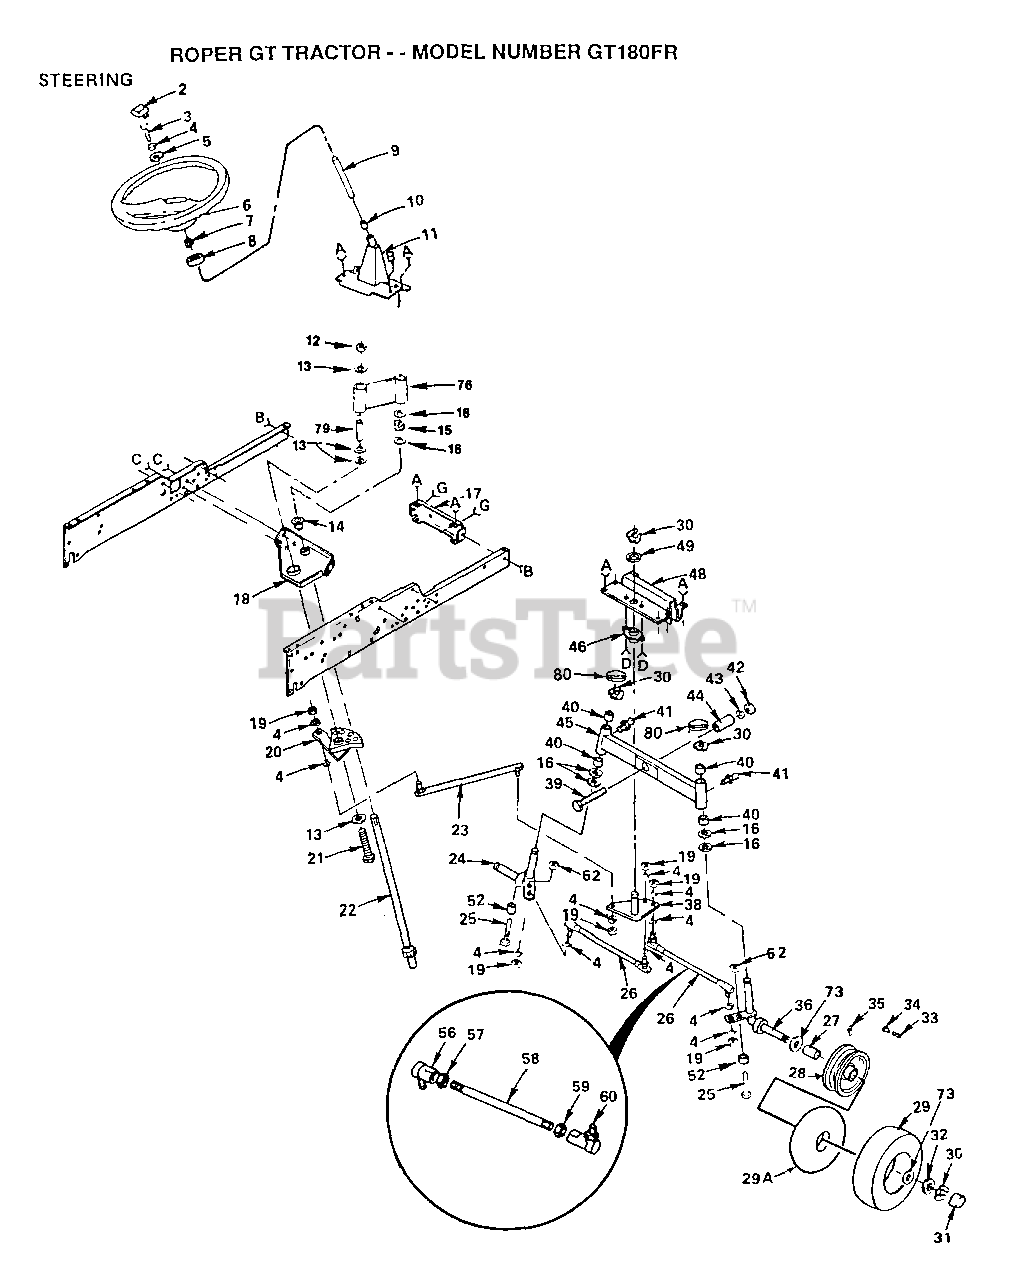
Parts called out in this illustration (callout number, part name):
2	INSERT STEERING
3	BOLT
4	LOCKWASHER
5	WASHER T
7	ADAPTER LT
9	TUBE
10	"T, BEARING"
11	SUPPORT ASSY T
12	NUT LTV
13	WASHER GT
14	"FLANGE GT, BEAR."
15	KLIP RING
16	WASHER .T
17	FRAME BRACKET GT
20	SECTOR T
21	BOLT T
22	SHAFT STEERING GT
23	LINK.DRAG.T
24	SPINDLE ASSY T
25	BOLT, HEX 3/8 - 16 X 2
26	TIE ROD T
27	"FLANGE, BEARING"
29A	TUBE.16X6.5/7.5-8
30	RING
31	HUB CAP
33	VALVE CAP
34	VALVE STEM LT
35	FITTING LT
36	SPINDLE RH T
38	"T, BELLCRANK"
39	BOLT
40	BRNG. T
41	ZERK M
42	NUT X
43	WASHER
45	AXLE ASSEMBLY
48	AXLE BRACKET T
49	WASHER
57	NUT
59	NUT
76	COLLAR
79	TUBE T
80	CAP
